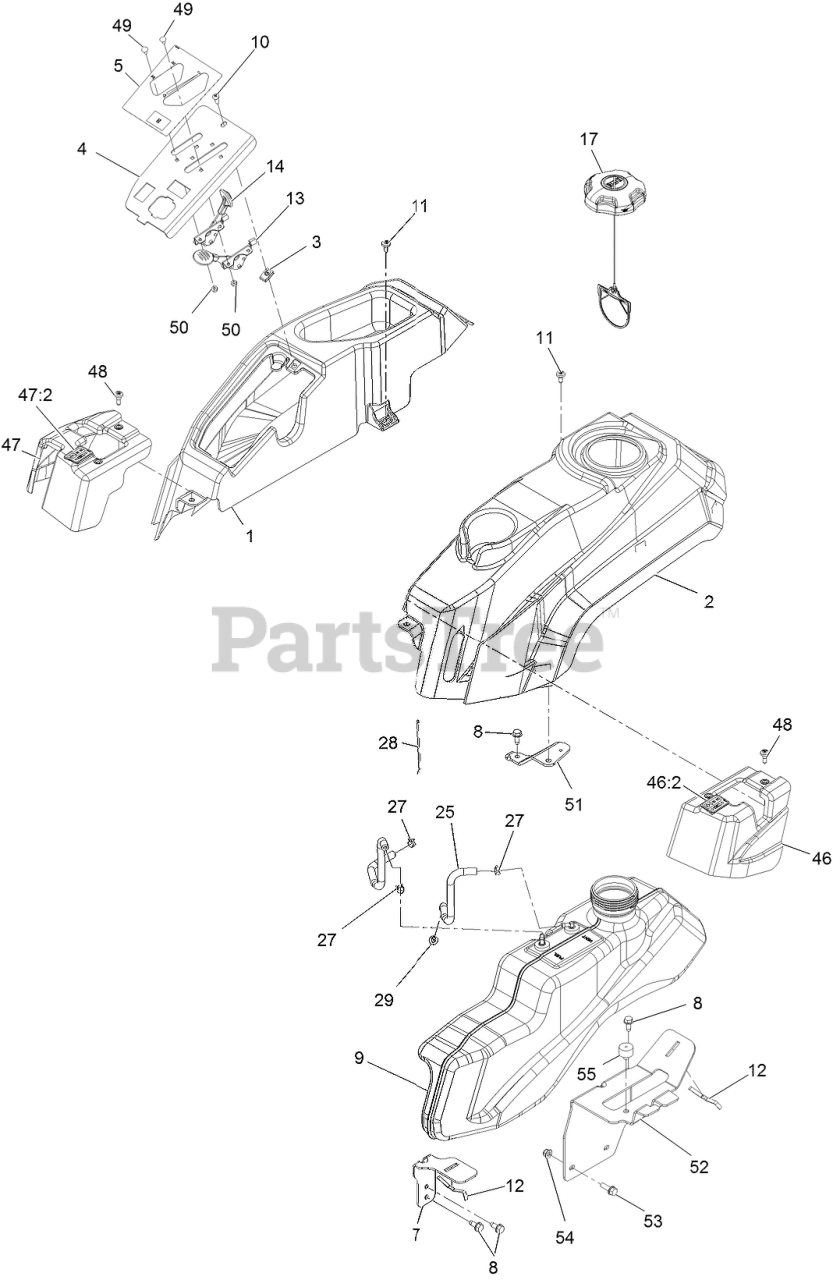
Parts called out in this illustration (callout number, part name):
1	POD-RH, NARROW
2	POD-LH, NARROW
4	PANEL-CONTROL, NARROW
5	DECAL-CONTROL
7	SUPPORT-TANK
8	Screw-HWH 5/16-18 X 3/4 Tf
9	TANK, FUEL
10	SCREW-PRH
11	SCREW-SHOULDER
12	SPRING
13	CABLE-CONTROL, THROTTLE
14	CABLE-CONTROL, CHOKE
17	CAP-FUEL, RATCHETING
25	HOSE-FUEL
27	CLAMP-HOSE
28	TIE-CABLE
29	ADAPTOR-ORIFICE
46	ASM, POD MC W/DECAL LH
46:2	DECAL-MOTION CONTROL
47	ASM, POD MC W/DECAL RH
47:2	DECAL-MOTION CONTROL
48	SCREW-SHOULDER
49	BOLT-CARR
50	NUT-LOCK, NI
51	BRACKET-CLAMP
52	BRACKET-SUPPORT TANK
53	SCREW-HHF
54	NUT-HF, NI
55	BUMPER-GROMMET
